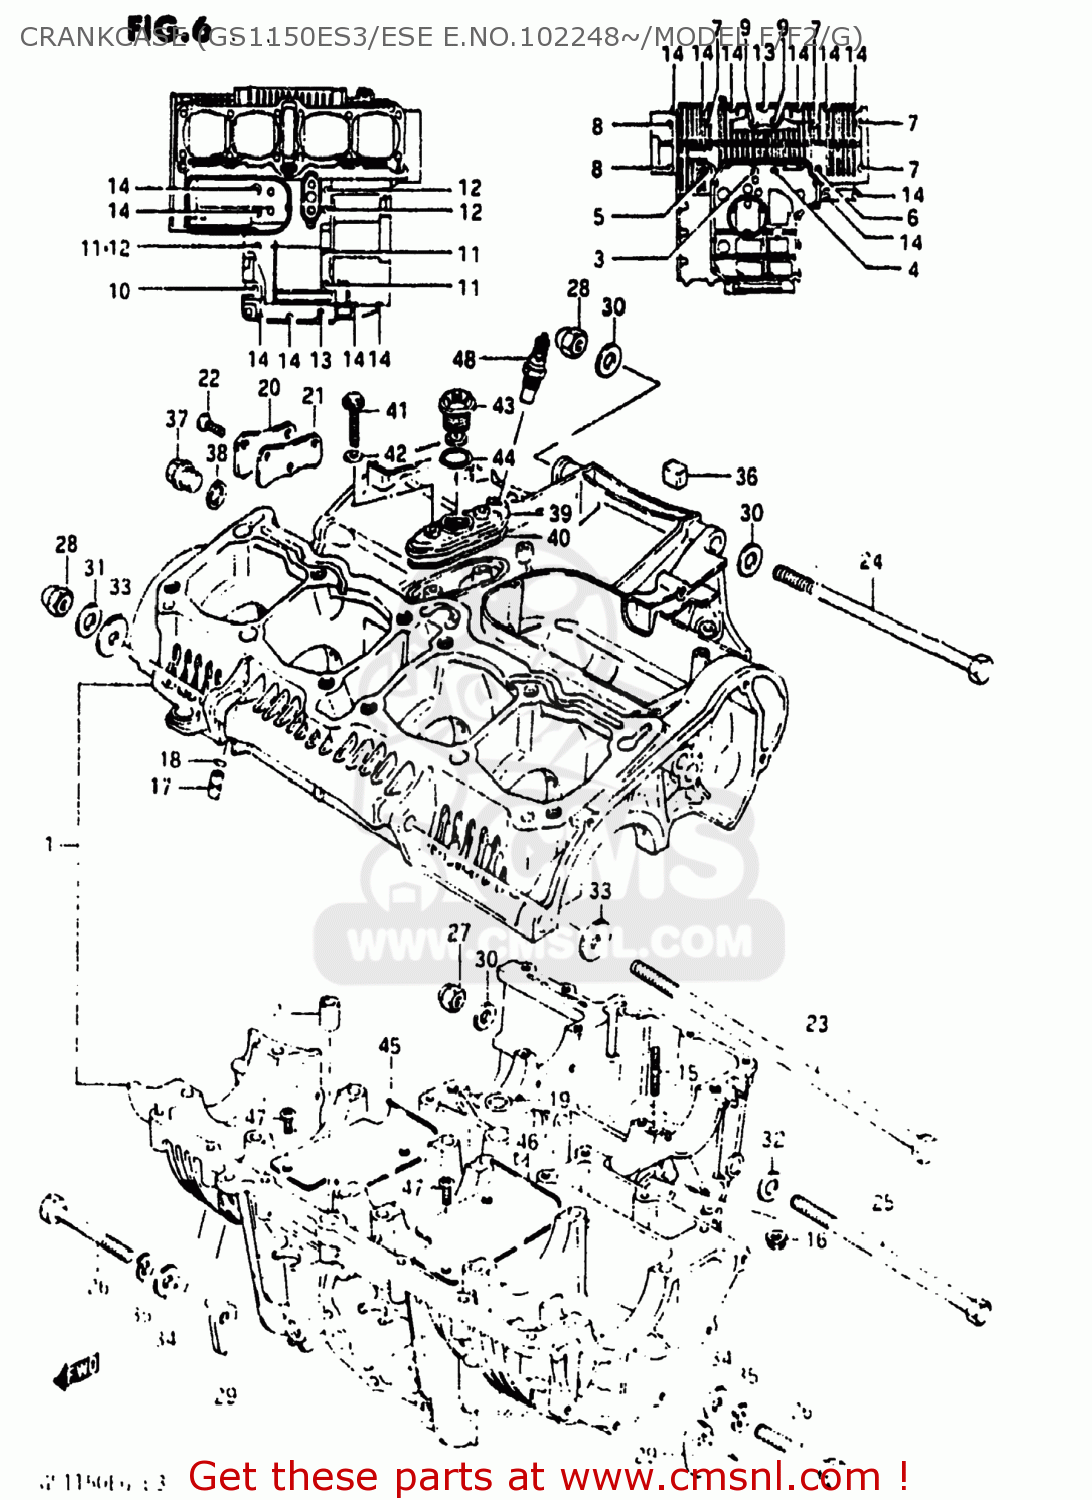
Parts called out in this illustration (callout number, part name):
1	CRANKCASE SET
2	PIN
3	BOLT(9X180)
4	BOLT(9X135)
5	BOLT(8X115)
6	BOLT(8X100)
7	BOLT 8X90
8	BOLT(8X65)
9	BOLT(9X60)
10	BOLT 8X60
11	BOLT
12	BOLT (6X75)
13	BOLT 6X55
14	BOLT
15	STUD 6X50
16	NUT
17	UNION
18	O RING(D:1.05,ID:3.1)
19	O RING(D:3.2,ID:12.9)
20	CAP,OIL GALLERY
21	GASKET,OIL GALLERY (MCA)
22	SCREW
23	BOLT
24	BOLT 10X180
25	BOLT(10X165)
26	BOLT 10X60
27	NUT (10MM)
28	NUT
29	NUT
30	WASHER
31	WASHER
32	WASHER
33	WASHER
34	WASHER (10.5X20X3.2)
35	LOCK WASHER
36	PAD,CYLINDER
37	PLUG (14X12)
38	GASKET(14X19.2X2) (NAS)
39	HOUSING,OIL PRESSURE SWITCH
40	O RING,PRESSURE SWITCH HOUSING
41	BOLT
42	WASHER
43	SWITCH ASSEMBLY
44	O RING(D:1.9,ID:18.8)
45	PLATE,OIL SEPARATOR
46	PLATE,OIL SEPARATOR
47	SCREW
48	GAUGE ASSEMBLY,OIL TEMPERATURE
